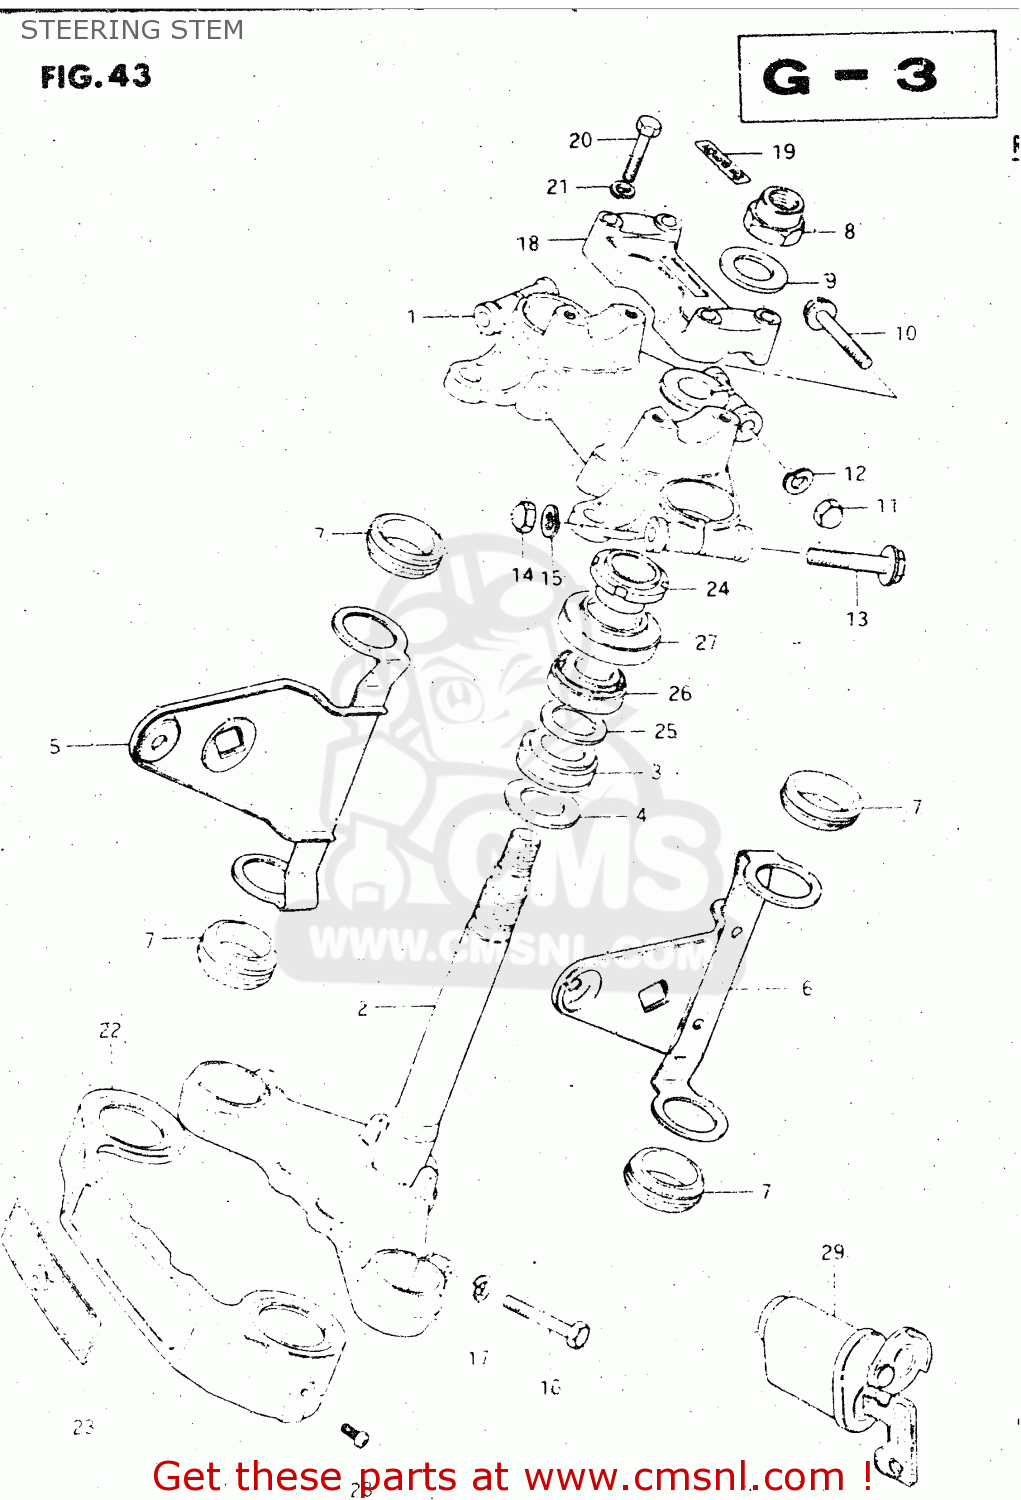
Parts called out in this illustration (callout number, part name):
1	HEAD,STEERING STEM
2	STEM,STEERING
3	BEARING
4	WASHER,THRUST
5	BRACKET,HEADLAMP,RIGHT
6	BRACKET,HEADLAMP,LEFT
7	CUSHION,HEADLAMP BRACKET
8	NUT,FR FORK UPR BRACKET
9	WASHER
10	BOLT
11	NUT,M8X1.25X12
12	LOCK WASHER
13	BOLT 10X55
14	NUT
15	LOCK WASHER
16	BOLT 10X40
17	LOCK WASHER
18	HOLDER,HANDLEBAR
19	EMBLEM,HANDLE CLAMP
20	BOLT
21	LOCK WASHER
22	COVER,FRONT FORK
23	EMBLEM
24	NUT,STEERING STEM
25	WASHER(18.5X24X1)
26	TAPER,ROLLER BEARING
27	DUST SEAL,STEERING UPR
28	SCREW 5X6
29	LOCK ASSY, STEERING (NEIMAN TYPE EXECUTE
